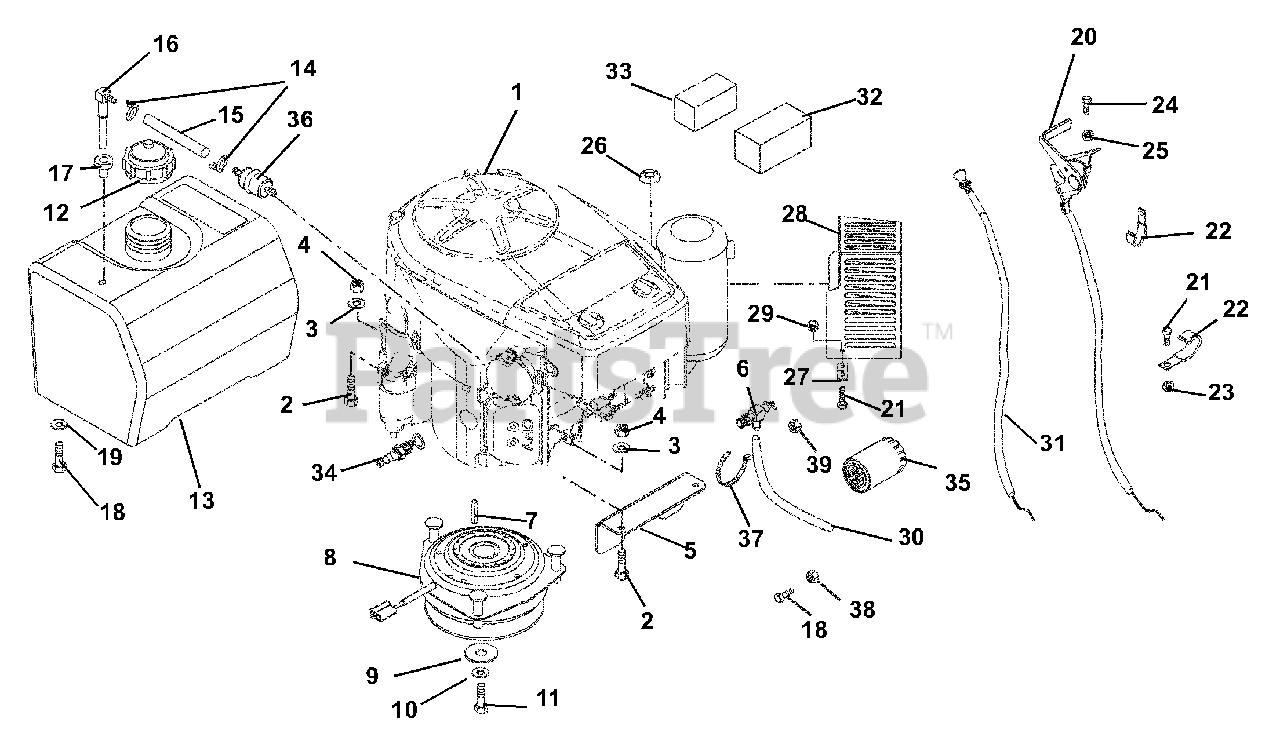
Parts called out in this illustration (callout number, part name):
1	ENGINE, 15 HP KAWASAKI
2	@BLT-HEX .31-18X1.75 GR5 YWZC
3	@WSHR-LK .31X.078 REG YWZC
4	@NUT-HEX .31-18 YWZC
5	BRACKET, CLUTCH
6	VALVE, OIL DRAIN
7	KEY-SQ .25 X 1.25 X .25 SAE
8	CLUTCH, ELECTRIC
9	WSHR-FL-STL .469X2.00X.25 YWZC
10	@WSHR-LK .44X.109 REG YWZC
11	BLT-HEX .44-20X3.00 GR5 YWZC
12	CAP - FUEL
13	TANK - FUEL
14	CLAMP-HOSE WIRE .490/.510X.116
15	GAS LINE-BULK 1/4" I.D.
16	FITTING, TANK
17	BSHG-FLG .375 X 1.062 X .625 R
18	@BLT-HEX .38-16X.75 GR5 YWZC
19	@WSHR-LK .38X.094 REG YWZC
20	CABLE - THROTTLE W/LINER
21	@BLT-HEX .31-18X.75 GR5 YWZC
22	J-CLAMP
23	@NUT-LK-NYL .312-18 YWZC
24	@SCR-MCH 10-24X.75 HWH YWZC
25	@NUT-LK-NYL 10-24 W/INSRT YWZC
26	WSHR-FL-STL .328X.87X.179 YWZC
27	BRACKET, MUFFLER GUARD
28	GUARD, MUFFLER
29	@NUT-LK-CTR .31-18 YWZC
30	TUBE, OIL DRAIN 8" CLEAR VINYL
31	CONTROL,CHOKE
32	AIR FLTR,PAPER KAWASAKI
33	AIR FLTR,FOAM KAW
34	PLUG, SPARK
35	FILTER,OIL - KAW
36	FUEL FILTER - KAWASAKI
37	CABLE TIE LG 5-1/2
38	@NUT-LK-CTR .38-16 YWZC
39	@NUT-LK-CTR .31-18 YWZC
